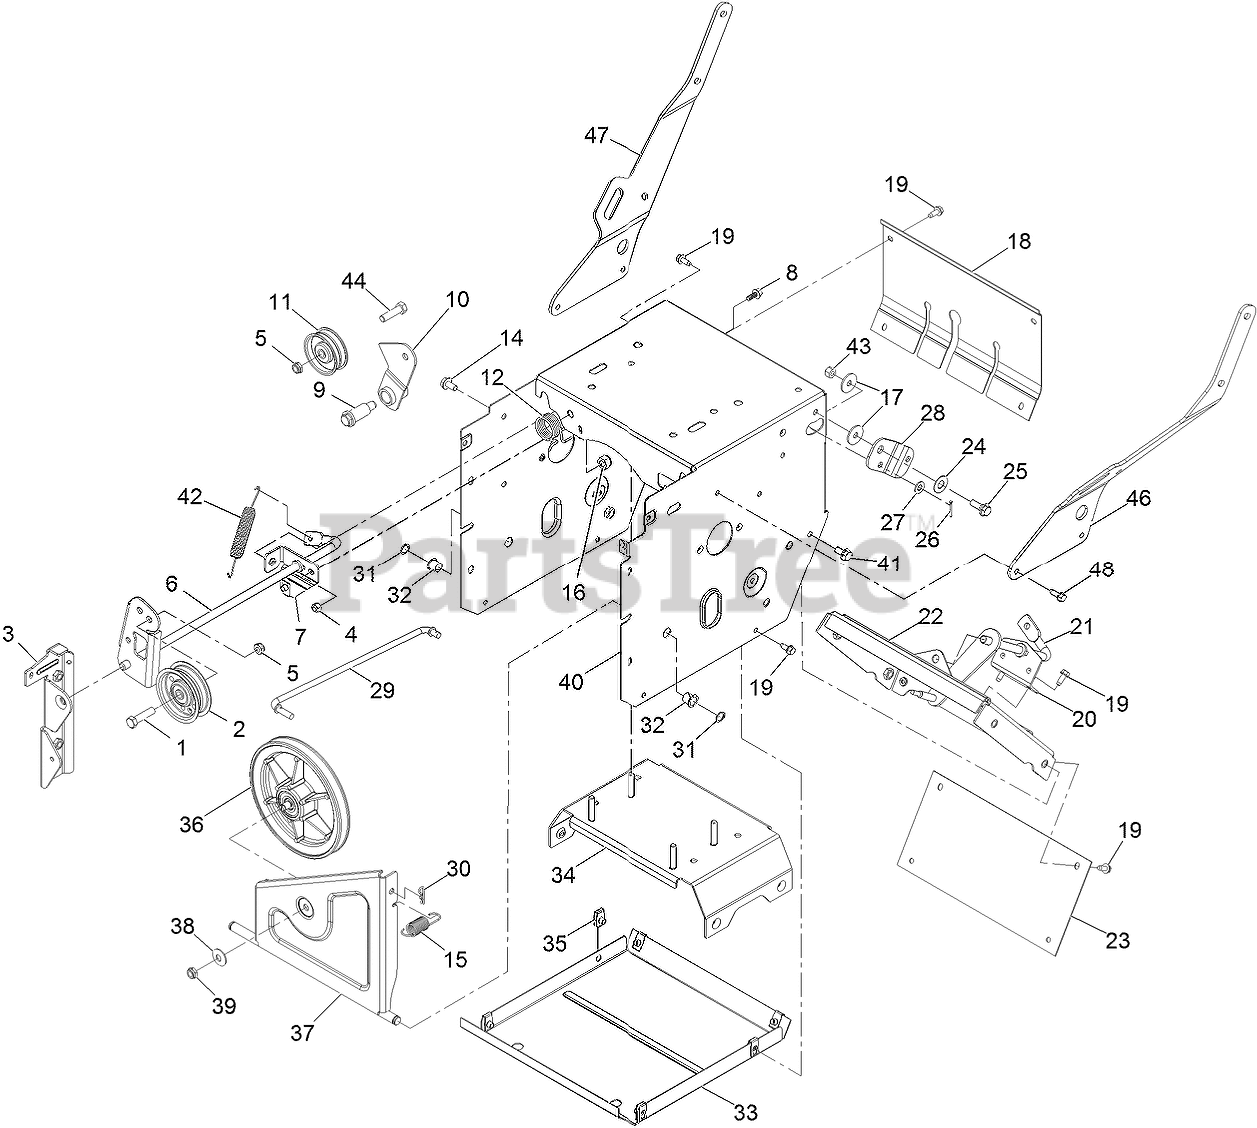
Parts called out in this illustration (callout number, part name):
1	SCREW-HH
2	PULLEY-IDLER
3	BRACKET-IMPELLER, IDLER
4	NUT-LOCK, NI
6	IMPELLER CLUTCH ASM
7	BRACKET-IMPELLER, CLUTCH
8	SCREW-HHF
9	BOLT-SHOULDER
10	ARM-IDLER, TRACTION
11	PULLEY-IDLER
12	SPRING-TORSION
14	SCREW-HHF
15	SPRING-EXTENSION
16	NUT-LOCK, NI
17	WASHER-PIVOT
18	COVER-UPPER
19	SCREW-HWH
20	BRACKET-SHIFT, ROD
21	TRACTION LEVER ASM
22	SHIFT PLATE ASM
23	COVER-LOWER
25	SCREW-SHOULDER
26	PIN-COTTER
27	WASHER-PLAIN
28	BELLCRANK
29	LINK-SPEED, CONTROL
31	RING-RETAINING
32	BUSHING-NYLINER
33	PAN-BOTTOM
34	BRACE-FRAME
36	PULLEY-TRACTION ASM
37	BRACKET-WHEEL, FRICTION
38	WASHER-BELLEVILLE
39	NUT-HEX
40	TRACTION FRAME ASM
41	SCREW-HWHTF
42	SPRING-EXTENSION
43	NUT-LOCK, NI
44	SCREW-HH
46	BRACE-HANDLE, LH
47	BRACE-HANDLE, RH
48	SCREW-HWH, THREAD ROLL
